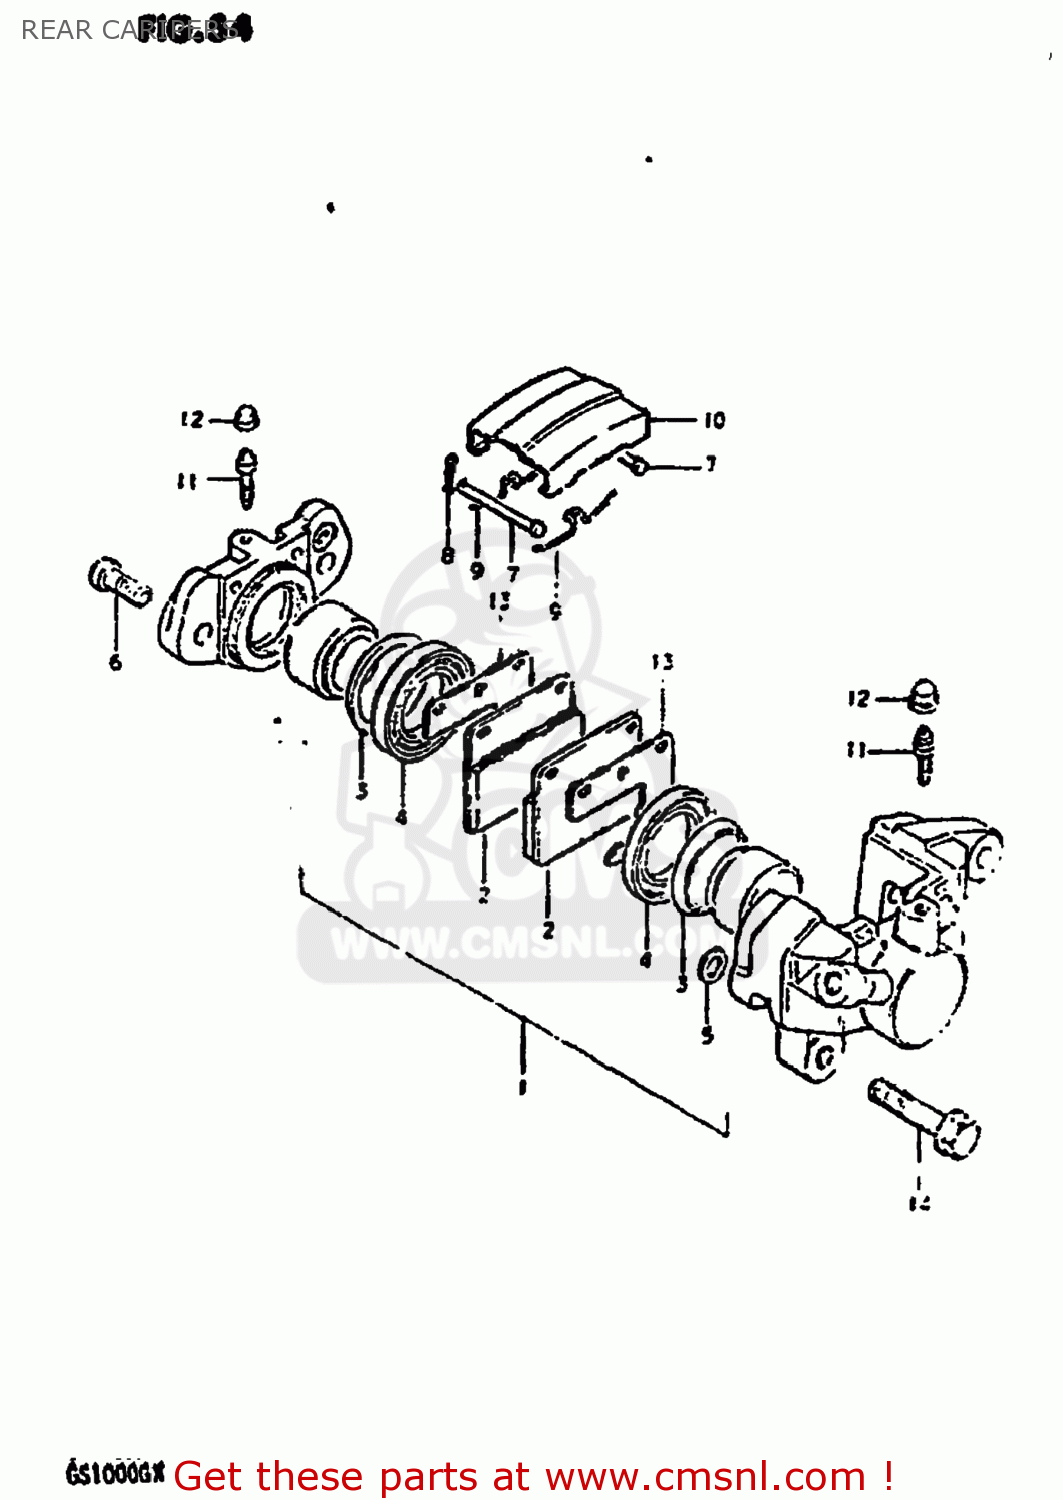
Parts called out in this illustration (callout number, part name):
1	PISTON SET
2	PAD,BRAKE
3	SEAL,PISTON
4	BOOT,PISTON
5	SEAL,PISTON
6	BOLT,HOUSING
7	PIN,PAD
8	CLIP,PAD PIN
9	SPRING
10	COVER,DUST
11	BLEEDER
12	CAP,BREATHER
13	SHIM,RR CALIPER
14	BOLT
